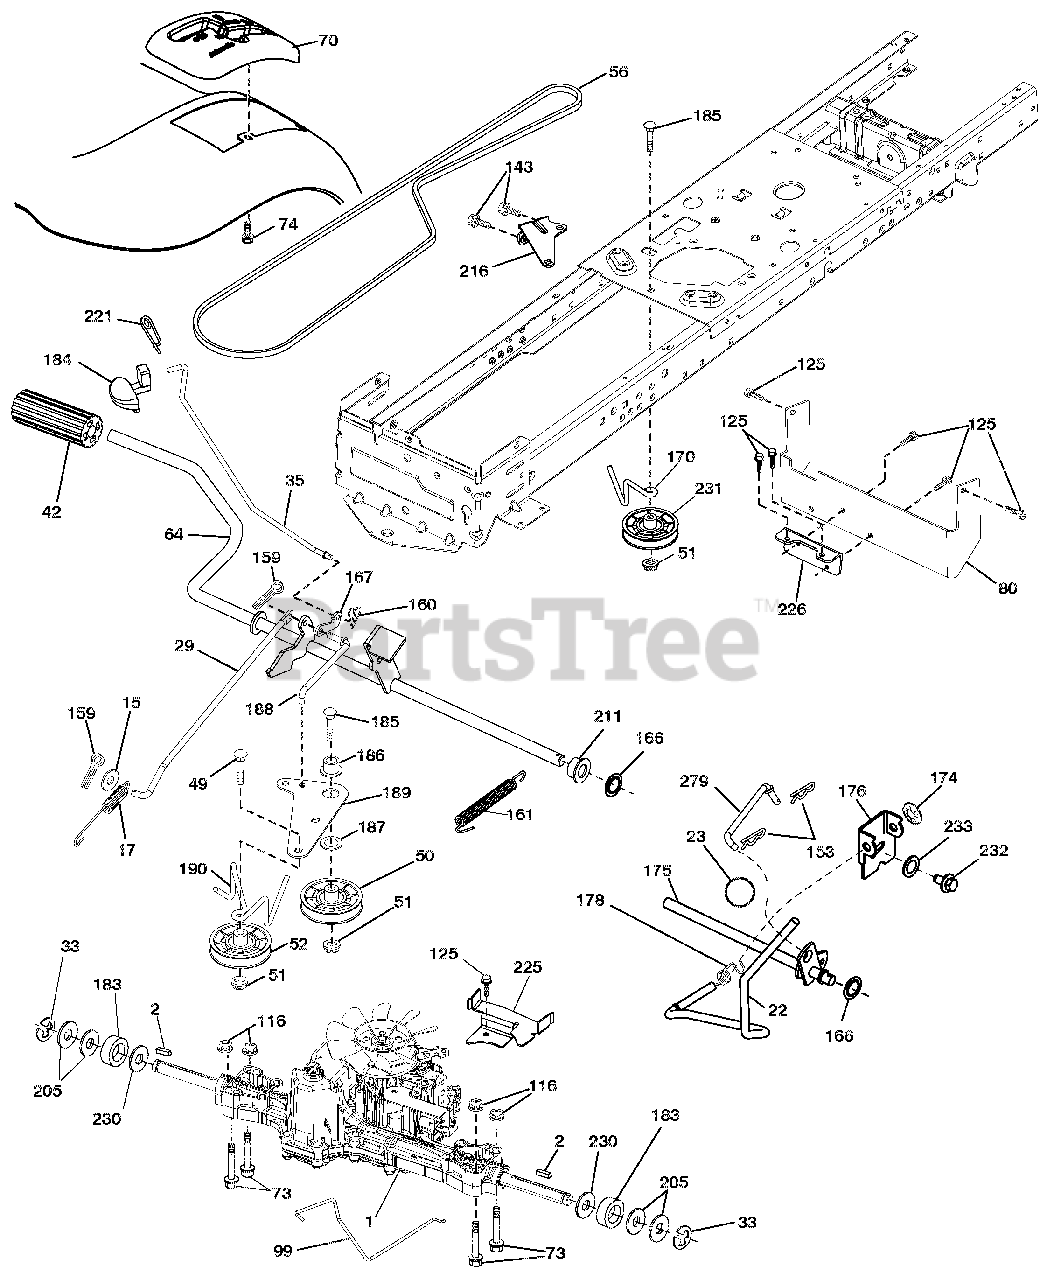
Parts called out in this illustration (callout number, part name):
1	TRANSAXLE, TUFFTORQ K46 BT(ORDER PARTS FROM TRANSAXLE MANUFACTURER)
2	KEY.SQUARE.2.0 X .1845/.1865
15	WASHER.13/32 X 13/16 X 16 GA.
17	SPRING.BRAKE.K46.GREEN
26	SPRING.RETURN.CRUISE
29	ROD.BRAKE.K46
33	E-RING.#5133-75
35	ROD.BRAKE.PARKING.LT.TEX
42	COVER.PEDAL.BLK.ROUND
49	BOLT.RDHD.3/8-16UNCX1-3/4.GR5
50	IDLER.FLAT.910"OFFSET
51	Nut, Hex, Flangelock 3/8-16
52	IDLER.V-GROOVE.910"OFFSET
56	V-BELT.MOWER.92.40.42/K46
64	SHAFT ASM.PEDAL.BRK.CNTRL.PCH
73	BOLT.HEX.FLGHD.5/16-18.GR.5
80	STRAP.TORQUE.K46/18"TEX
92	Bolt, Hex Head 5/16-18 x 1-1/4
99	ROD.SPRING.BYPASS.K46.LT.Z
116	Nut, Lock Hex Flange 5/16-18 u
125	SCREW.5/16-18X3/4.SMGML.TAP/BL
143	SCREW.THDROL.5/16-18 X 1/2TYTT
153	Retainer Spring
159	PIN.COTTER.1/8 X 3/4.CAD.
160	RETAINER.CLIP(M).DIA.290
161	SPRING.RETURN.CLUTCH.6.75
163	ROD.CONTROL.PEDAL.K46
166	NUT PUSH .625
167	LATCH.BRAKE.PARKING
170	KEEPER.CENTER SPAN.1.688
183	SPACER.AXLE.HYDRO/PEERLES
184	HANDLE.PARKING BRAKE.LTTEX.505
185	BOLT.RDHD.3/8-16UNC X2-3/4 GR5
186	SPACER.RETAINER
187	WASHER.13/32 X 2 X 10 GA.
188	LINK.CLUTCH.GROUND DRIVE
189	BELLCRANK.GROUNDRIVE.NSTG/NSTL
190	KEEPER.BELLCRANK.DRIVE.GROUND
196	SCREW.3/8-16X1.SMGML.TAP/R.BLK
197	LINK.CLUTCH.ANTI-ROTATIN.1"CRK
205	WASHER.25/32 X 1-5/8 X 16GA.
206	BRACKET.MOUNT.LATCH.CRUISE
207	LATCH.CONTROL.CRUISE
208	GEAR SECTOR.CONTROL.CRUISE
209	ROD.CONTROL.CRUISE.LT.ELITE
210	ROCKER ASM.PEDAL CONTROL.TEXLT
211	BEARING.NYLON.BLK..629 ID.
213	HANDLE.CONTROL.CRUISE.ELTE.428
214	PAD PEDAL FORWARD
215	PEDAL.REVERSE.TEX.GT.428
216	BRACKET.PULLEY.IDLER.WTEX
221	RETAINER.SPRING.CLIP.HANDLE
222	WASHER.21/32X1-1/4.10GA.N/PLTD
225	KEEPER.BELT.TRANSAXLE.K46
226	BRACKET.MOUNT.TORQUE.K46.TLT
230	WASHER.HARDEN..793 X 1.637X060
231	IDLER.V-GROOVE.1.688"OFFSET
